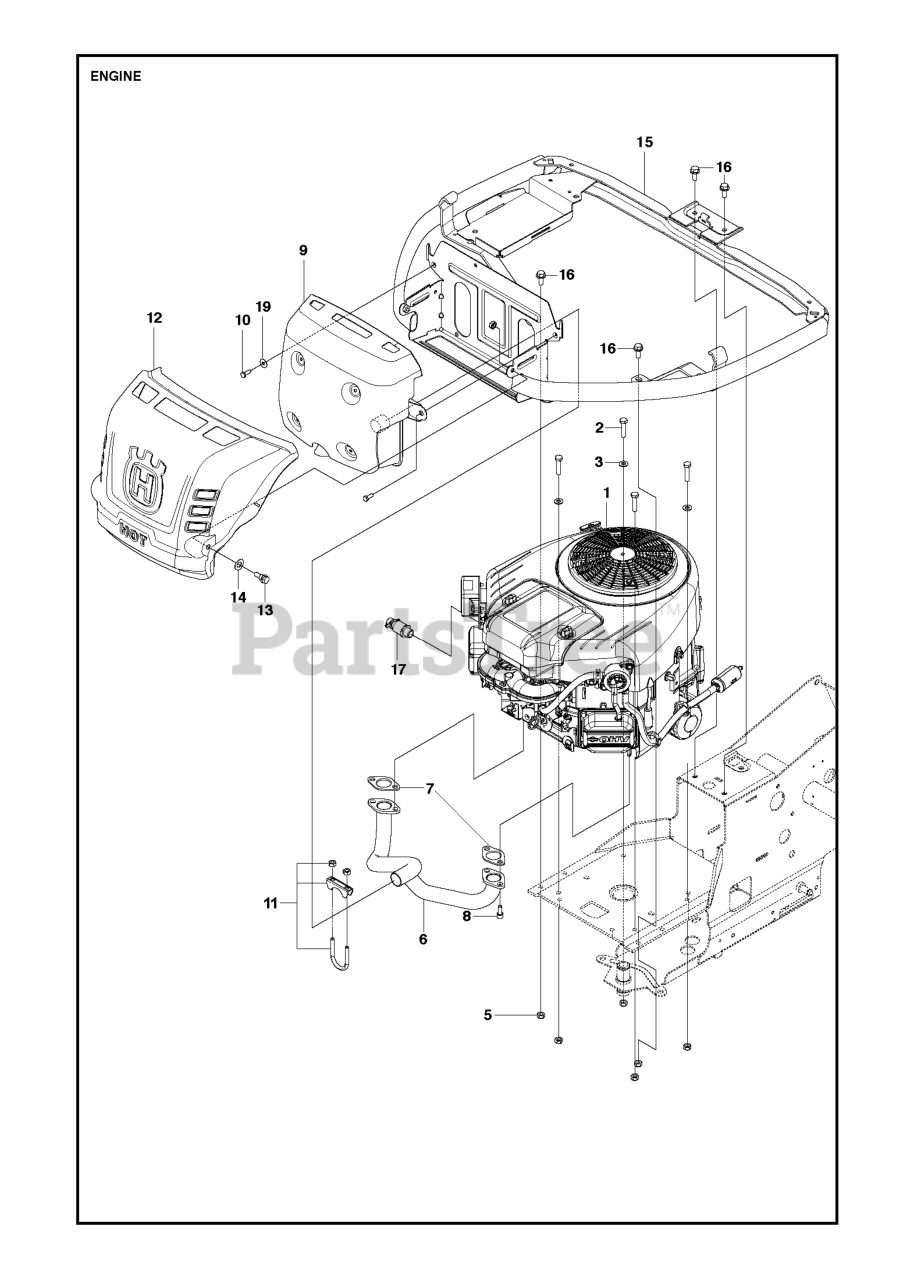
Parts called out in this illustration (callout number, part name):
2	STUD SCREW
2	SCREW
3	WASHER BRB 8.4X17
5	LOCKNUT M8
6	Mainfolds
6	MANIFOLD
7	FLANGE
8	BOLT
9	MUFFLER
11	CLAMP ASSY EXHAUST
12	HEAT SHIELD
14	SPRINGWASHER
17	VALUE.OIL.DRAIN
19	WASHER - 26X6.5X1.6
